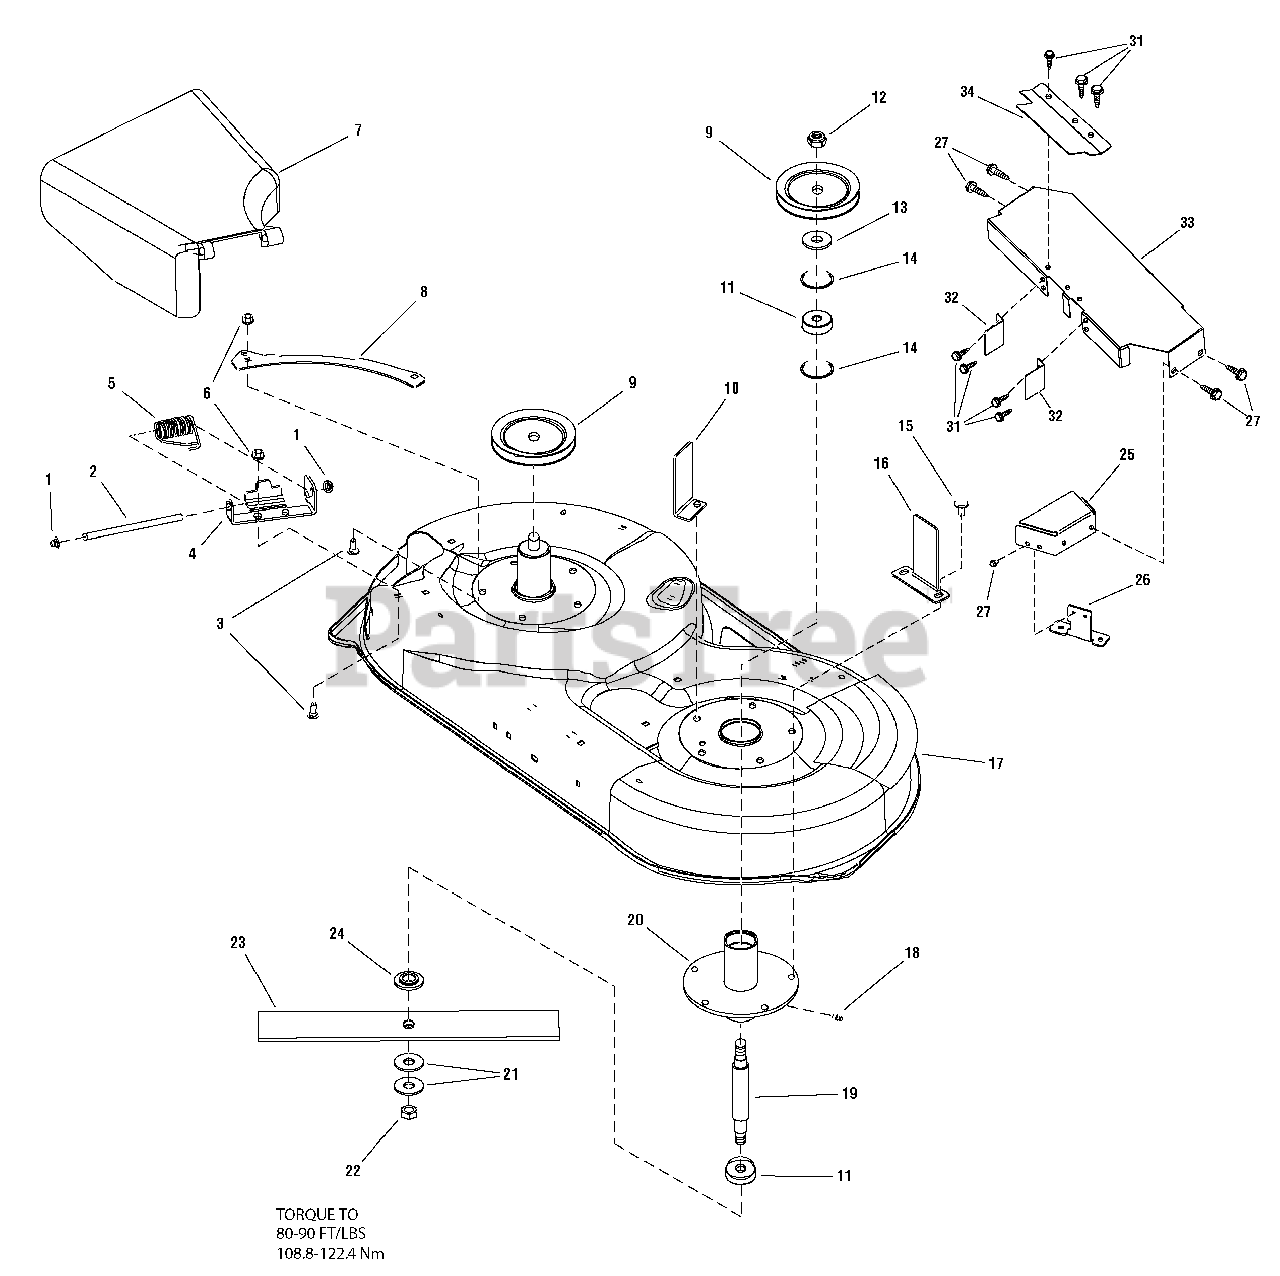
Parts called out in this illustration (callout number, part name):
1	NUT, Push, 3/8
2	ROD, Deflector
3	BOLT, Carriage, 5/16-18 x 3/4
4	BRACKET, Hinge 9GA
5	SPRING, Torsion
6	NUT, Hex, Flange Whizlock, 5/16-18
7	DEFLECTOR & SUPPORT ASSEMBLY, Chute Riveted
8	PLATE, Rear
9	PULLEY, 5.25
10	UPSTOP, "L" 10GA
11	BEARING, Upper
12	NUT, Hex Lock, ESNA Light, 5/8-18, Thin
13	SPACER, Pulley, 1.755" OD, .655" ID, .280" Thick
14	RETAINING RING, Extension, 1-3/4
15	SCREW, Hex, Washer Head, Taptite, 3/8-16 x 3/4
16	UPSTOP, "L" 10GA
17	HOUSING, 38"
18	FITTING, Grease
19	SHAFT, Spindle, 7.181" Long
20	TUBE & PLATE ASSEMBLY, Spindle
21	WASHER, Belleville
22	NUT, Hex 9/16-18
23	BLADE, 38" Mower, 19.49" Long
24	WASHER, Spindle Blade Powdered Metal
25	COVER, Spindle
26	SUPPORT, Spindle Cover
27	SCREW, Tapitite 1/4-20 x 1/2
31	RIVET
32	GUARD, Belt
33	GUARD
34	GUARD, Belt
